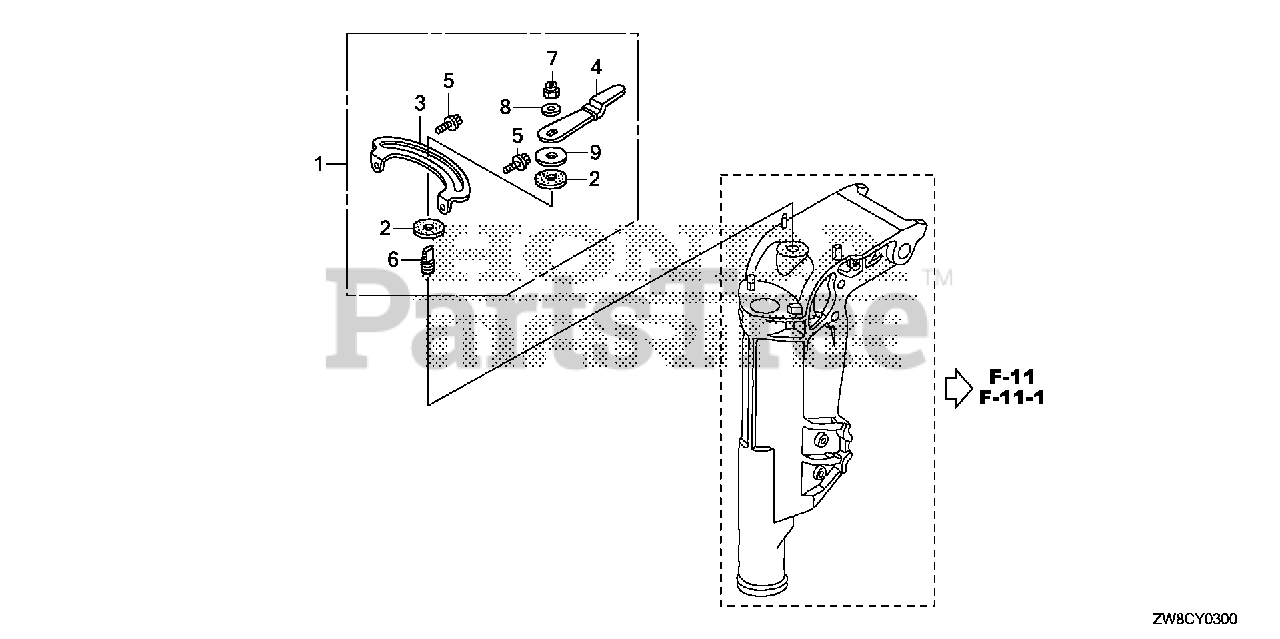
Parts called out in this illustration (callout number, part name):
1	STEERING KIT, FRICTION
2	BLOCK, FRICTION
3	PLATE, FRICTION
4	LEVER, FRICTION
5	BOLT, FLANGE (6X12)
6	BOLT, STUD (8X26)
7	NUT, SELF-LOCK (8MM)
8	WASHER (8MM)
9	WASHER, NYLON (8MM)
